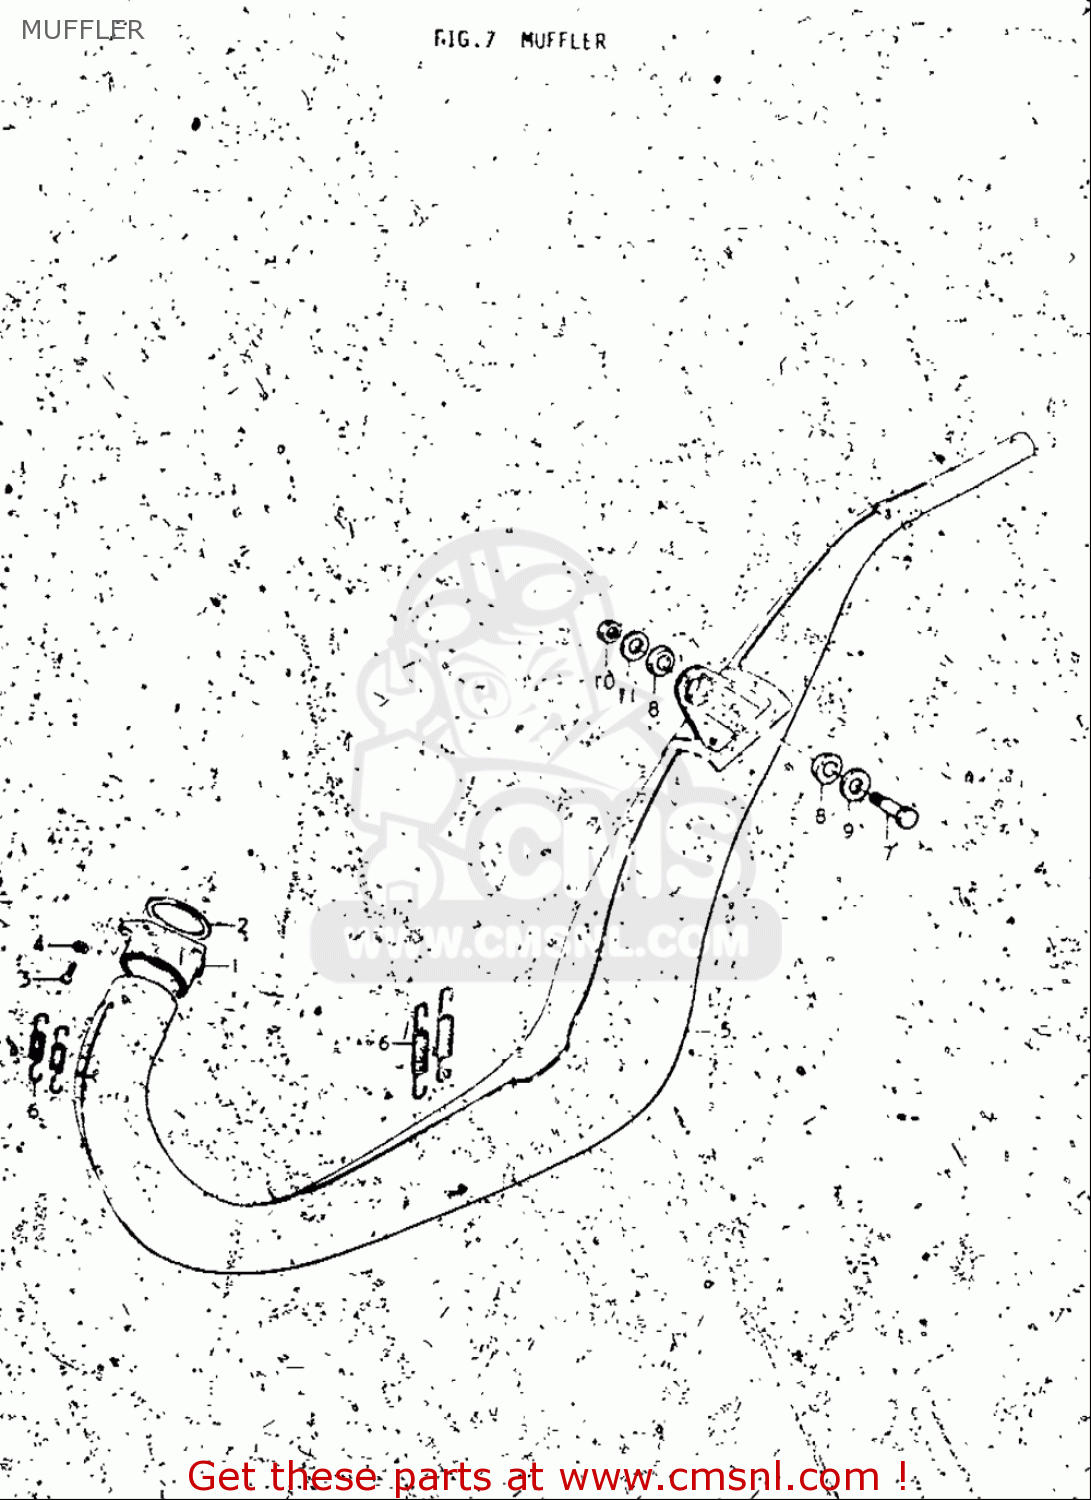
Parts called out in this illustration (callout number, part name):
2	GASKET,EXHAUST PIPE (NAS)
3	SCREW
4	WASHER,LOCK
6	SPRING
7	BOLT
9	WASHER (8.2X22X3.2)
10	NUT
11	WASHER
